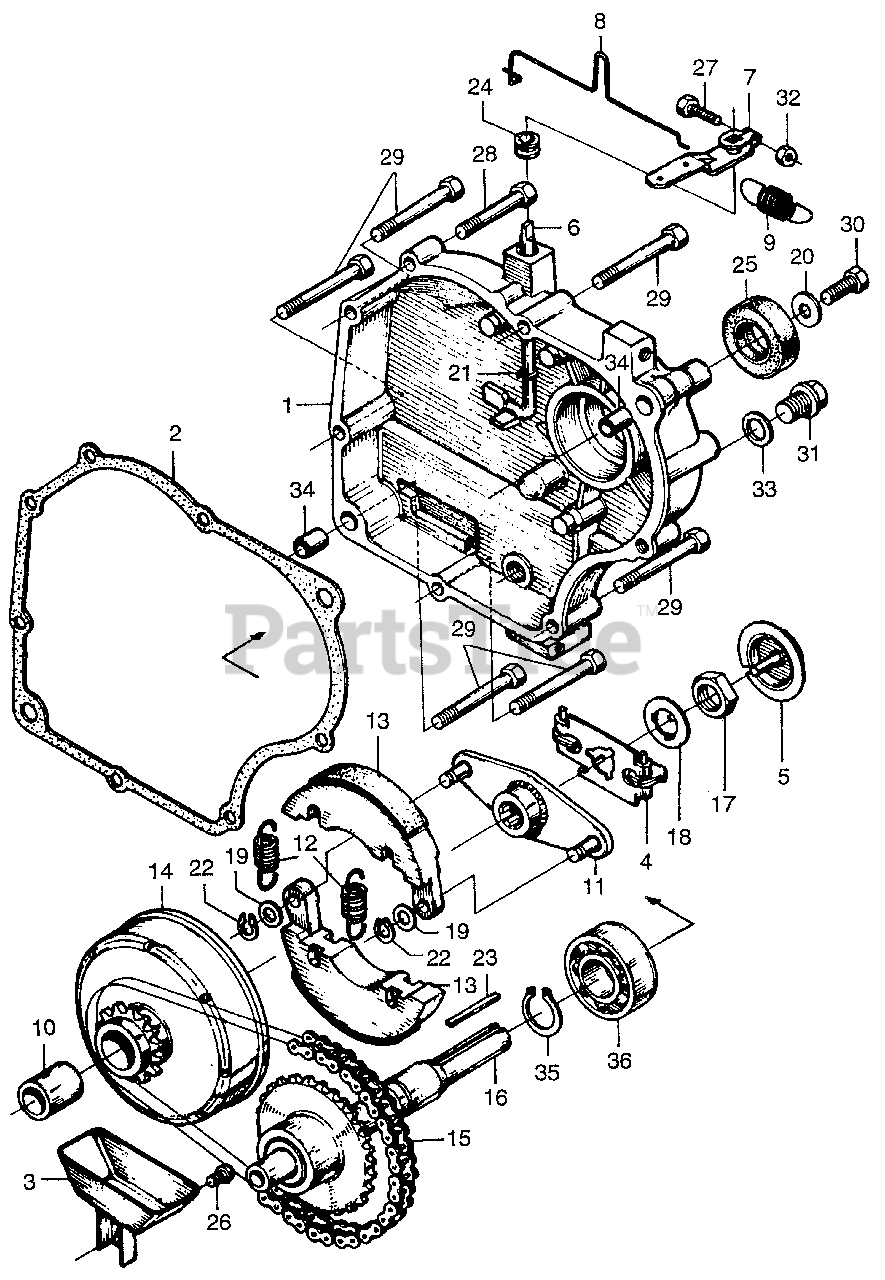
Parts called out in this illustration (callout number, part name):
1	COVER, R. CRANKCASE
1	COVER, R. CRANKCASE (NOT AVAILABLE)
2	GASKET, CASE (NOT AVAILABLE)
3	SEPARATOR, CLUTCH
4	HOLDER, GOVERNOR WEIGHT (NOT AVAILABLE)
5	SLIDER, GOVERNOR (NOT AVAILABLE)
6	SHAFT, ARM (NOT AVAILABLE)
7	ARM, GOVERNOR (NOT AVAILABLE)
8	ROD, GOVERNOR (NOT AVAILABLE)
9	SPRING, GOVERNOR (NOT AVAILABLE)
10	GUIDE, CLUTCH CENTER
11	PLATE, DRIVE (NOT AVAILABLE)
12	SPRING, CLUTCH (NOT AVAILABLE)
13	WEIGHT, CLUTCH (NOT AVAILABLE)
14	SPROCKET, DRIVE
15	CHAIN A, DRIVE
16	SHAFT D, P.T.O. (NOT AVAILABLE)
17	NUT, LOCK (14MM)
18	WASHER, LOCK (14MM)
19	WASHER (8MM) (NOT AVAILABLE)
20	WASHER (8MM)
21	CIRCLIP (5MM) (NOT AVAILABLE)
22	CIRCLIP (OUTER) (8MM)
23	KEY (5X5X33)
25	OIL SEAL (25X40X7)
26	BOLT, HEX. (5X8)
27	BOLT, HEX. (5X14)
28	BOLT, HEX. (6X32)
29	BOLT, HEX. (6X45)
30	BOLT, HEX. (8X20)
31	BOLT, DRAIN PLUG
32	NUT, HEX. (5MM) (NOT AVAILABLE)
33	WASHER, DRAIN PLUG (12MM)
34	PIN A, DOWEL (10X16)
35	CIRCLIP (OUTER) (25MM)
36	BEARING, RADIAL BALL (6005)
